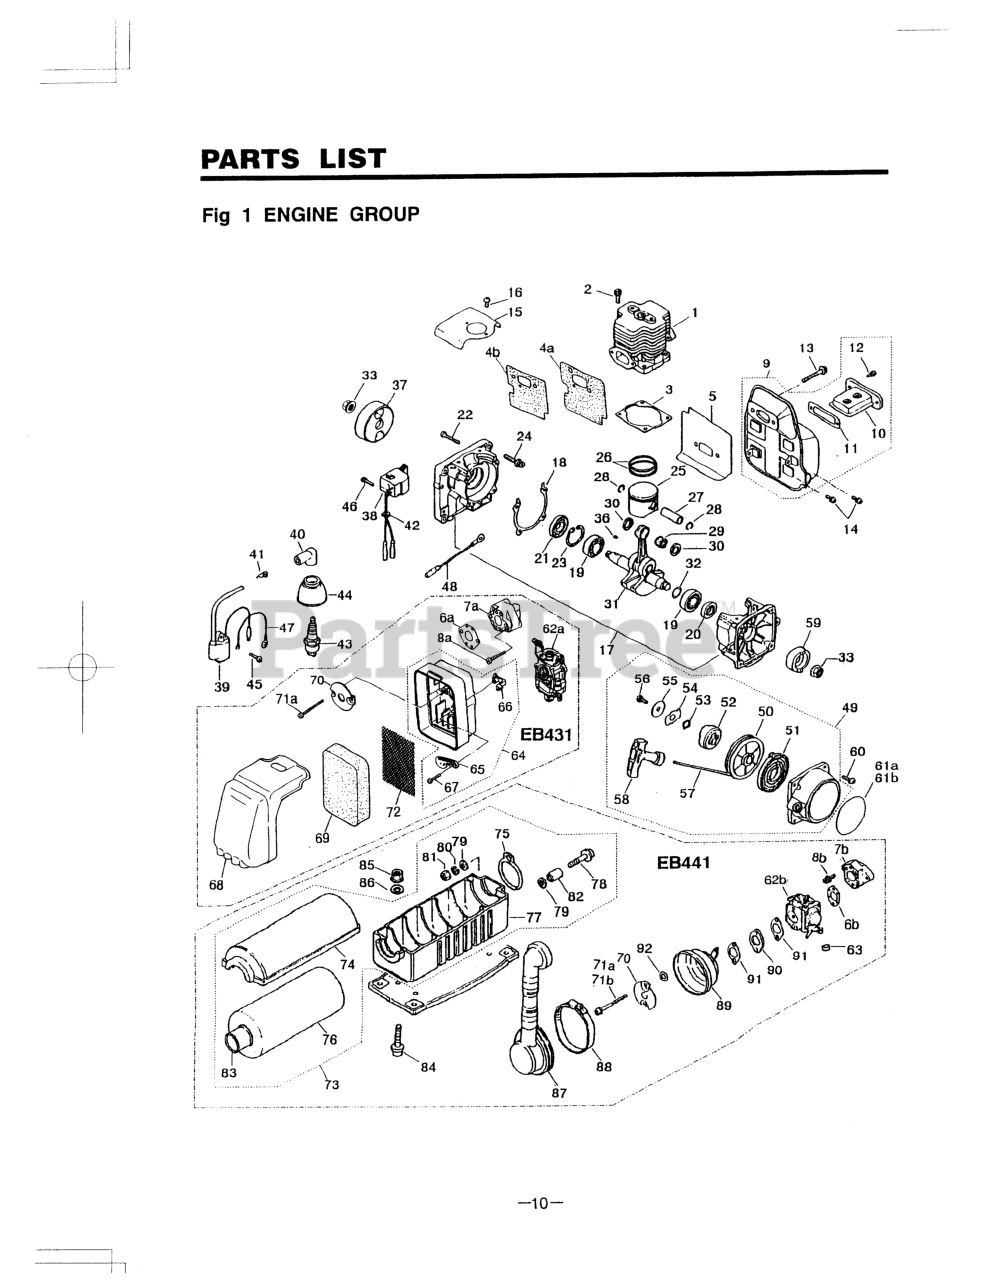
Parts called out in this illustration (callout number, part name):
1	CYLINDER (RPLS -12111)
8A	SCREW, M5 x 35
9	MUFFLER (RPLS -15101)
10	ARRESTER
12	SCREW, M4 x 10
17	CRANKCASE
20	SEAL, OIL - STARTER SIDE
22	BOLT, M5 X 30
23	RING, SNAP, M35 X 1.5
26	RING, PISTON (RPLS -41210)
27	PIN, PISTON (RPLS. 1490-41316)
28	RING, SNAP
29	BEARING
30	WASHER (RPLS 1491-41510)
31	SHAFT (RPLS -42001)
32	SHIM (REPLACES 848-870-G000)
33	NUT, M10
36	KEY
39	COIL, IGNITION
41	SPRING
42	GROMMET
44	CAP (NO LONGER AVAILABLE)
45	SCREW, M4 x 16
46	BOLT, M4 X 16
47	CABLE COMPLETE
51	SPRING (RPLS -75220)
52	DOG
54	RETAINER (RPLS 1861-75161)
55	WASHER
56	SCREW
57	ROPE
58	KNOB
59	PULLEY (RPLS -75210)
60	BOLT, M5 x 20
62A	CARBURETOR ASSEMBLY
65	PLATE
66	LEVER
67	SCREW (REPLACES 50030272)
69	ELEMENT (RPLS -82310)
70	PLATE (REPLACES -82511)
71A	SCREW, M5 x 60
NI	KIT, GASKET
